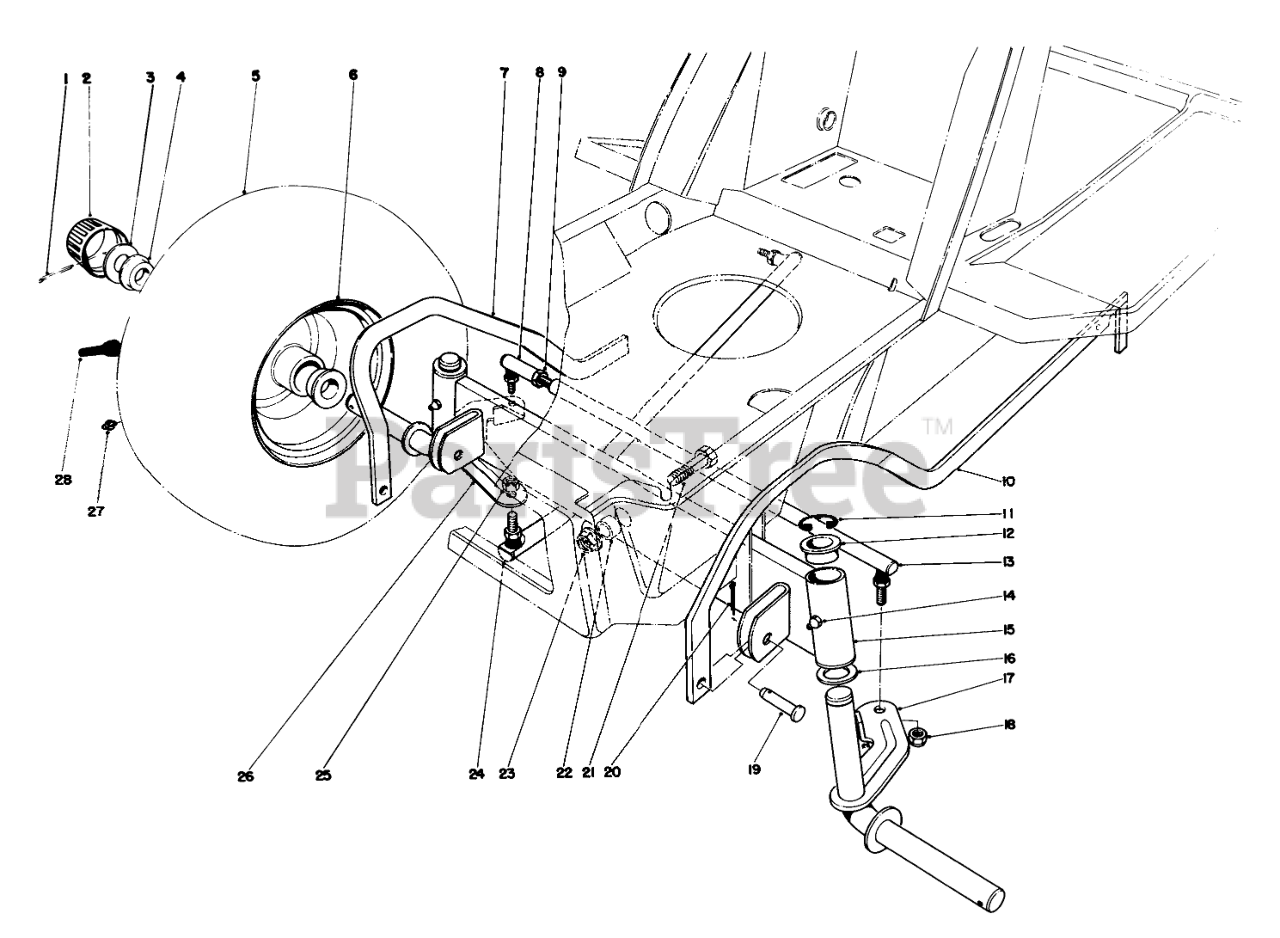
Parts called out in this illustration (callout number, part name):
1	PIN-COTTER
2	CAP-HUB
3	WASHER-PLAIN
4	Bearing
5	TIRE-FRONT
6	FRONT WHEEL
7	RH DECK PARALLEL LINK R
8	JOINT-BALL
9	NUT-JAM
10	LH DECK PARALEL LNKR
11	E-RING
12	BEARING-FLANGE
13	Tie Rod Steering (Incl. Ref. #8 & 9)
14	GREASE FITTING
15	Front Axle (Incl. Ref. #12)
16	WASHER-THRUST
17	Spindle L.H.
18	NUT-LOCK, NI
19	PIN-CLEVIS
20	PIN-COTTER
21	SCREW-HH
22	SPACER-AXLE, FRONT
23	NUT-HF
24	STEERING ARM B
25	NUT-HEX
26	SPINDLE WA RH B
27	FITTING-GREASE
28	STEM-VALVE
